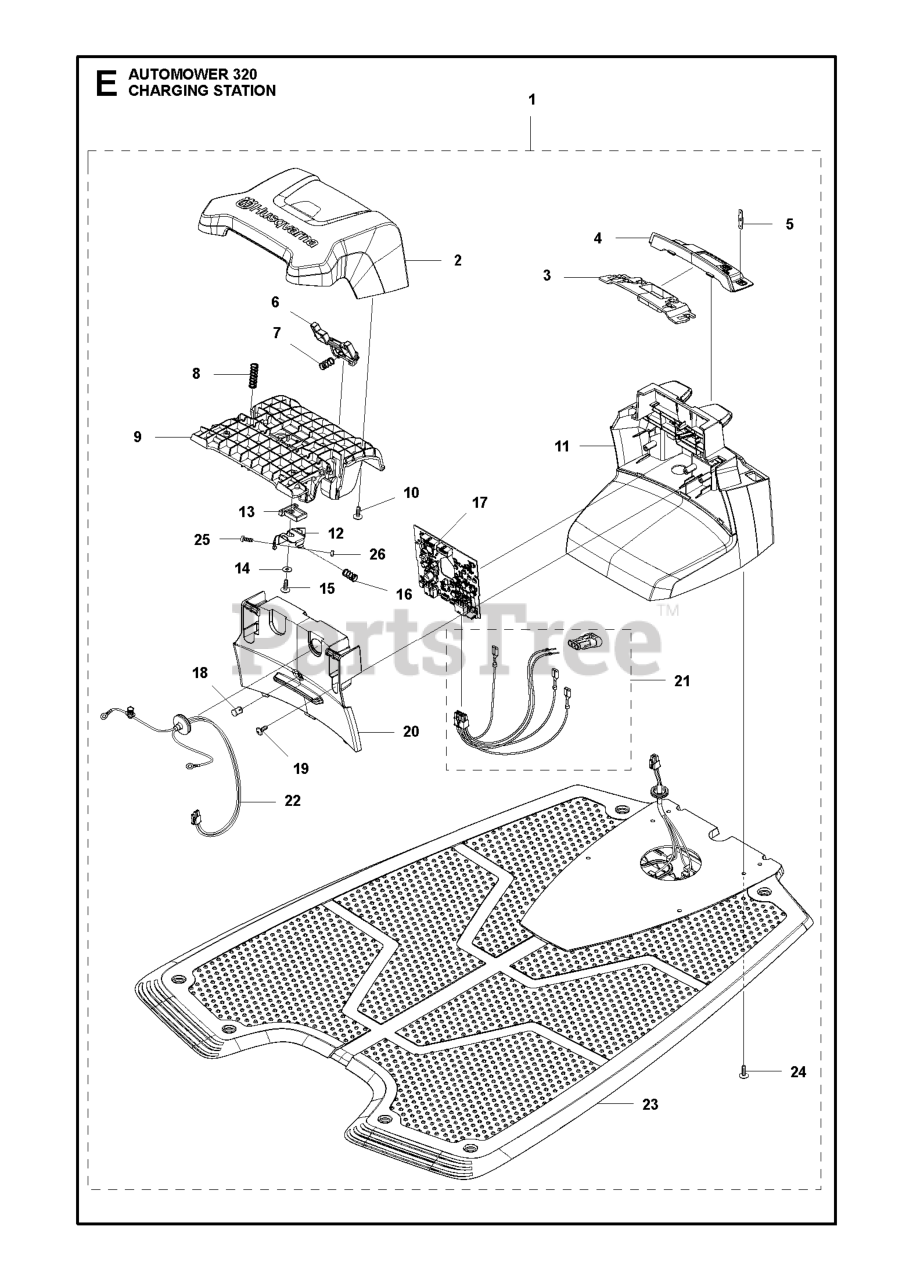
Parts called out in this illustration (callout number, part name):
2	CAP CHARGING STATION
3	HOLDER CHARGING STATION
4	PAN CHARGING STATION 320, ONE
5	TERMINAL TERMINAL CHARGING STA
6	BUTTON CHARGING STATION, RELEA
7	SPRING STOP BUTTON
8	SPRING SPRING CAP
10	SCREW 14MM
13	DISTANCE CHARGING STATION
15	SCREW 14MM
16	SPRING SPRING CAP
18	LENS
19	SCREW 14MM
20	LID CHARGING STATION 320, ONE
23	CHARGING PLATE
24	SCREW 14MM
25	SCREW ITXPANM M4X12 8.8 ZP-BC
26	NUT M4
